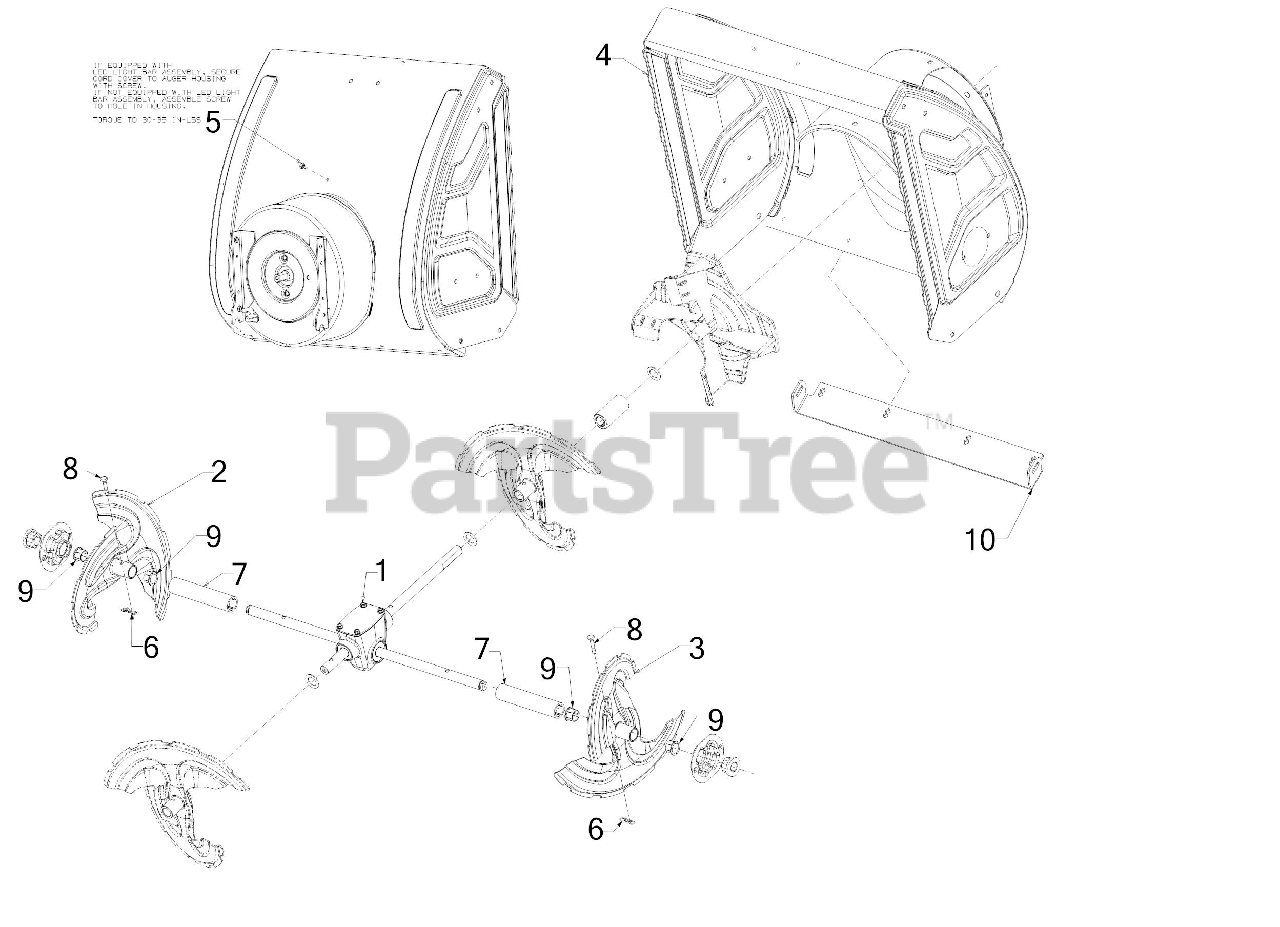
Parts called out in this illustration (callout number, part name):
1	24" AUGER GEARBOX ASSEMBLY
2	SPIRAL ASSEMBLY (RH)
3	SPIRAL ASSEMBLY (LH)
4	24" HD LED AUGER HOUSING ASSEMBLY
5	SCREW M6-1 x .625
6	BOW TIE COTTER PIN 1/4-5/16
8	SHEAR PIN .25 x 1.50 GR2
9	FLANGE BUSHING
10	SHAVE PLATE 23.50
